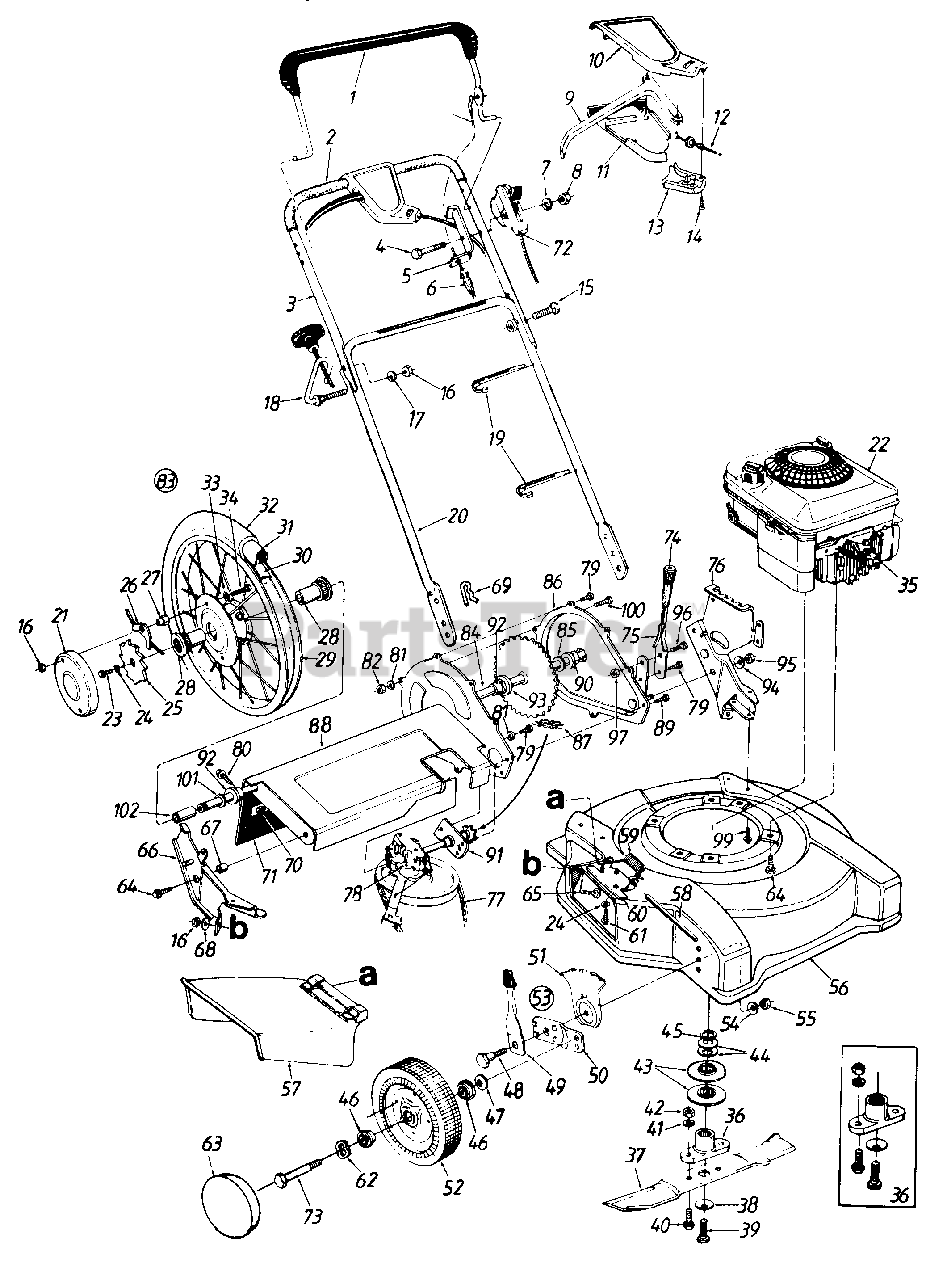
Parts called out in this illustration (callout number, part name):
1	Control Handle Ass'y.
2	Foam Grip
3	Upper Handle
4	Hex Bolt 1/4-20 x 2.0" Lg.
5	Cable Mtg. Brkt.
6	Control Cable-36" Lg.
7	Spring Wash. .265" I.D.
8	Hex Nut 1/4-20 Thd.
9	Control Lever
10	Control Cover Half-Upper
11	Control Cover Half-Lower
12	Self-Propelled Cable-44" Lg.
13	Cable Mounting Cap
14	Fl-"C" Sunk Hd. Tap Scr. #10 x .75" Lg.
15	Curved Carr. Bolt 5/16-18 x 1.38" Lg.
16	Hex Nut 5/16-18 Thd.
17	L-Wash. 5/16" I.D.
18	Rope Guide Bolt
19	Cable Tie
20	Lower Handle
21	Wheel Cover
22	Engine
23	Hex Bolt 1/4-20 x .75" Lg. (Grade 5)
24	Bell-Wash. 1/4" I.D.
25	Wheel Ratchet
26	Pawl and Spring Ass'y.
27	Special Hex Nut 5/16-18 Thd.
28	Flange Bearing 63n I.D.
29	Rim Ass'y. Only 16" x 2.1"
30	Rimstrip 16" x 718"
31	Inner Tube 16" x 2.12"
32	Chevron Tire 16" x 2.125"
33	Intern. L-Wash. 5/16" I.D.
34	Hex Bolt 5/16-18 x 1.0" (Grade 5)
35	Spark Plug Boot
36	Blade Adapter Kit
37	22" Blade
38	Bell-Wash..46" I.D.
39	Hex Bolt 7/16-20 x 1.5" Lg. (Grade 5)
40	Hex Bolt 3/8-24 x 1" Lg.
41	L-Wash. 3/8" I.D.
42	Hex Nut 3/8-24 Thd.
43	Pulley Half
44	Bell-Wash. 1.01" I.D.
45	Crankshaft Spacer
46	Ball Bearing 1/2" I.D.
47	Bell-Wash..38" I.D.
48	Shld. Bolt .5"
49	Spring Lever Ass'y. w/Knob
51	Height Adj. Plate
52	Wheel Ass'y. Comp. 8" x 2"
53	Height Adj. Ass'y. Comp.-R.H.
54	Bell-Wash. .39" I.D. x 1.38"
55	Hex Nut 3/8-16 Thd.
56	22" Deck Ass'y.
57	Chute Deflector Ass'y.
58	Hinge Pin
59	Torsion Spring
60	Adapter Plate
61	Hex TT-Tap Scr. 1/4-20 x .5"
62	Wave Wash. .53" I.D. x .78"
63	Hub Cap
64	Hex TT-Tap Scr. 3/8-16 x 1"
65	Carriage Bolt 5/16-18 x .62" Lg.
66	Handle Brkt. Ass'y.-R.H.
67	Spacer .383" I.D. x .503"
68	Bell-Wash. 5/16" I.D.
69	Intern. Cotter Pin 5/16" Dia.
70	Retaining Strip
71	Rear Flap
72	Throttle Control Ass'y. Comp.- 49" Lg.
73	Front Axle Bolt
75	Height Adjustment Lever
76	Handle Brkt. Ass'y.-L.H.
77	"V" Belt
78	Transmission Comp.
79	Hex B-Tap Scr. 1/4 x .38" Lg.
80	Hex AB-Tap Scr. 1/4 x .62n Lg.
81	L-Wash. 1/4" I.D.
82	Hex Nut 1/4-20 Thd.
83	Wheel Ass'y. Comp.
84	Sprocket and Axle Ass'y.
85	Fl-Wash. .635" I.D. x 1.0" O.D.
86	Chaincase and Arm Ass'y.
87	#48 Chain 1/2" Pitch x 52 Links
88	Rear Drive Support Ass'y.
89	Hex Wash. Hd. TT-Tap Scr. 1/4-20 x .5" Lg.
90	Hex Flange Brg. .631 " I.D.
92	Hex Flange Brg. .631" I.D.
93	Spacer .63" I.D. x 1.25"
94	Fl-Wash. .385" I.D. x .87" O.D.
95	Hex L-Nut 3/8-24 Thd.
96	Hex Bolt 3/8-16 x .62" Lg.
97	Flanged L-Nut 3/8-16 Thd.
99	Hex B-Tap Scr. 5/16-18 x .5"
100	Hex Bolt 1/4-20 x .5" Lg.
101	Fl-Wash. .632" I.D. x .943"
102	Spacer .628" I.D. x.875"
